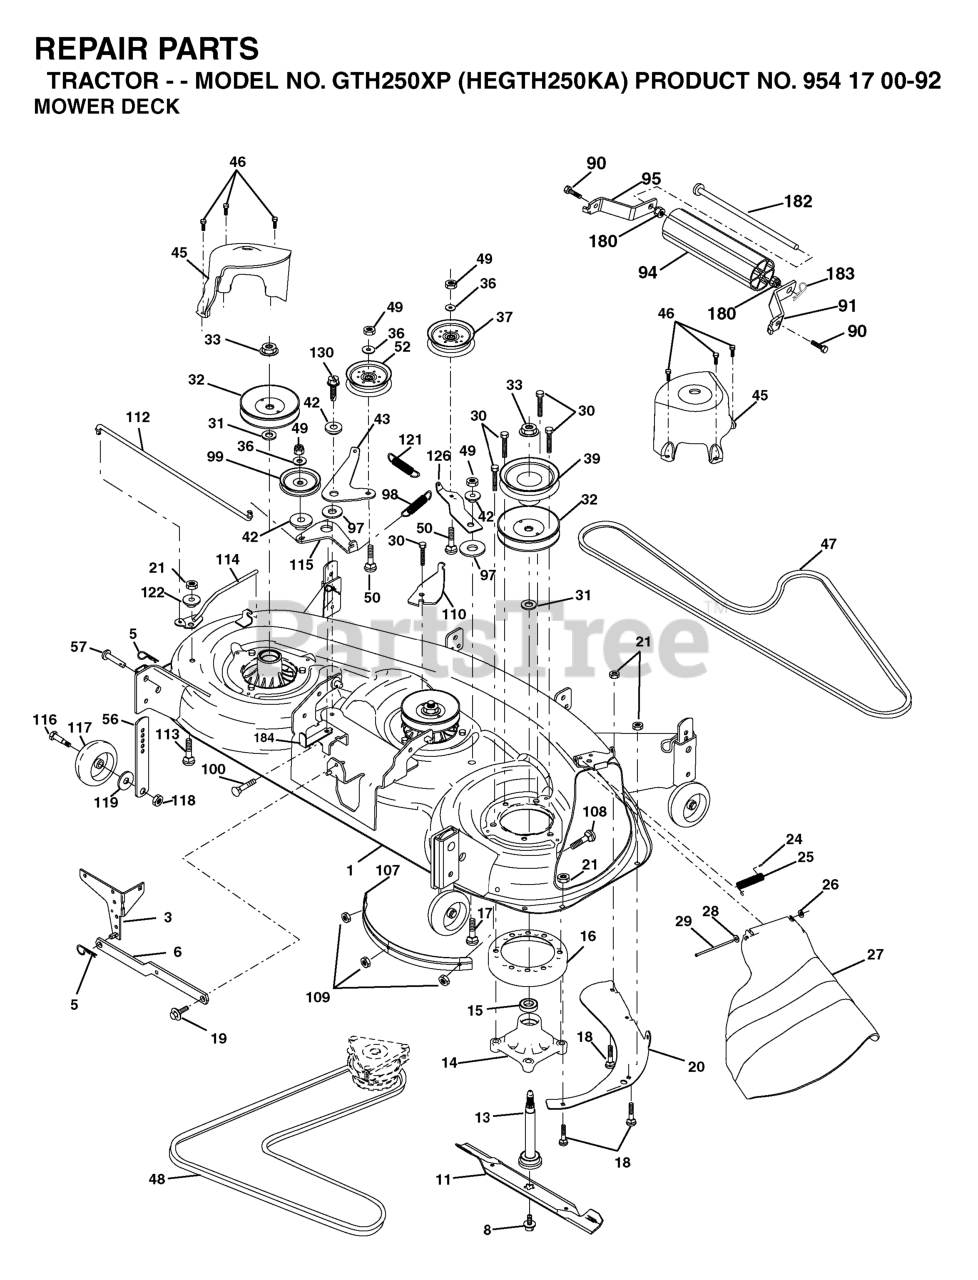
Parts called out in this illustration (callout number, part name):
1	DECK WELDMENT
3	BRACKET ASM.
5	RETAINER-SPRNG RB
6	BAR SWAY DECK
8	BOLT 7/16 ASM BLADE
11	48" HI-LIFT BLADE
13	SHAFT ASM W/LOWER BEARING
14	HOUSING, MANDREL 48"
16	STRIPPER.MANDREL.ROUND.BLACK
17	BOLT
18	BOLT
19	BOLT SHD 5/16-18
20	BAFFLE, VORTEX MWR
21	LOCKNUT
24	CAP-SLEEVE LT
25	SPRING, TORSION
26	NUT PUSH M
27	DEFLECTOR SUBS TO 532 180655
28	Washer 11/32 x 5/8 x 16 Ga SD
29	ROD.HINGE
30	SCREW, WASHER HEAD
31	WASHER
32	PULLEY, MANDREL
33	NUT, FLG TOPLOCK 9/16"
36	WASHER
37	PULLEY.IDLER.FLAT
39	PULLEY.DRIVEN.DECK.48'
42	SPACER.RETAINER.MOWER
43	ARM, IDLER SECONDARY
45	COVER.MANDREL.DECK.48"
46	SCREW.1/4-20X5/8
47	V-BELT, 48"SECONDARY
48	V-BELT PRIMARY 48"
50	BOLT.3/8-16X1.50
52	PULLEY.IDLER.FLAT.46.PR.DR.
56	BAR.ADJUST.WHEEL.ANTI.SCALP.BL
57	RIVET.PIN.HEAD.YELLOW.
90	BOLT RB
91	BRKT.NOSEROLLER.RH.48"
94	NOSE ROLLER 48"
95	BRKT.NOSEROLLER.LH.48"
98	SPRING PRIMARY DRIVE
99	IDLER PULLEY
110	ARM, SPRING SECONDARY
112	LEVER, TENSION RELIEF LINK
113	BOLT.CARR.SQNK.5/16-18UNC.X3/4
114	LEVER ASM, TENSION RELIEF
115	ARM, SPRING TENSION RELIEF
116	SHOULDER BOLT
117	RP WHEEL. GUAGE RALLY
118	LOCKNUT
119	WASHER.5/16.FLAT.STE.STD.
121	SPRING.DRIVE.SECONDARY.48".DEC
122	BUSHING, PIVOT TENSION RELIEF
126	ARM, IDLER PRIMARY DECK
130	SCREW 3/8-16X1
180	NUT.71038.31-18.HEX.NYLOCK
182	ROD.ROLLER.NOSE.NARROW.48"
183	SPRING RETAINER
184	KEEPER BELT IDLER PLATED
